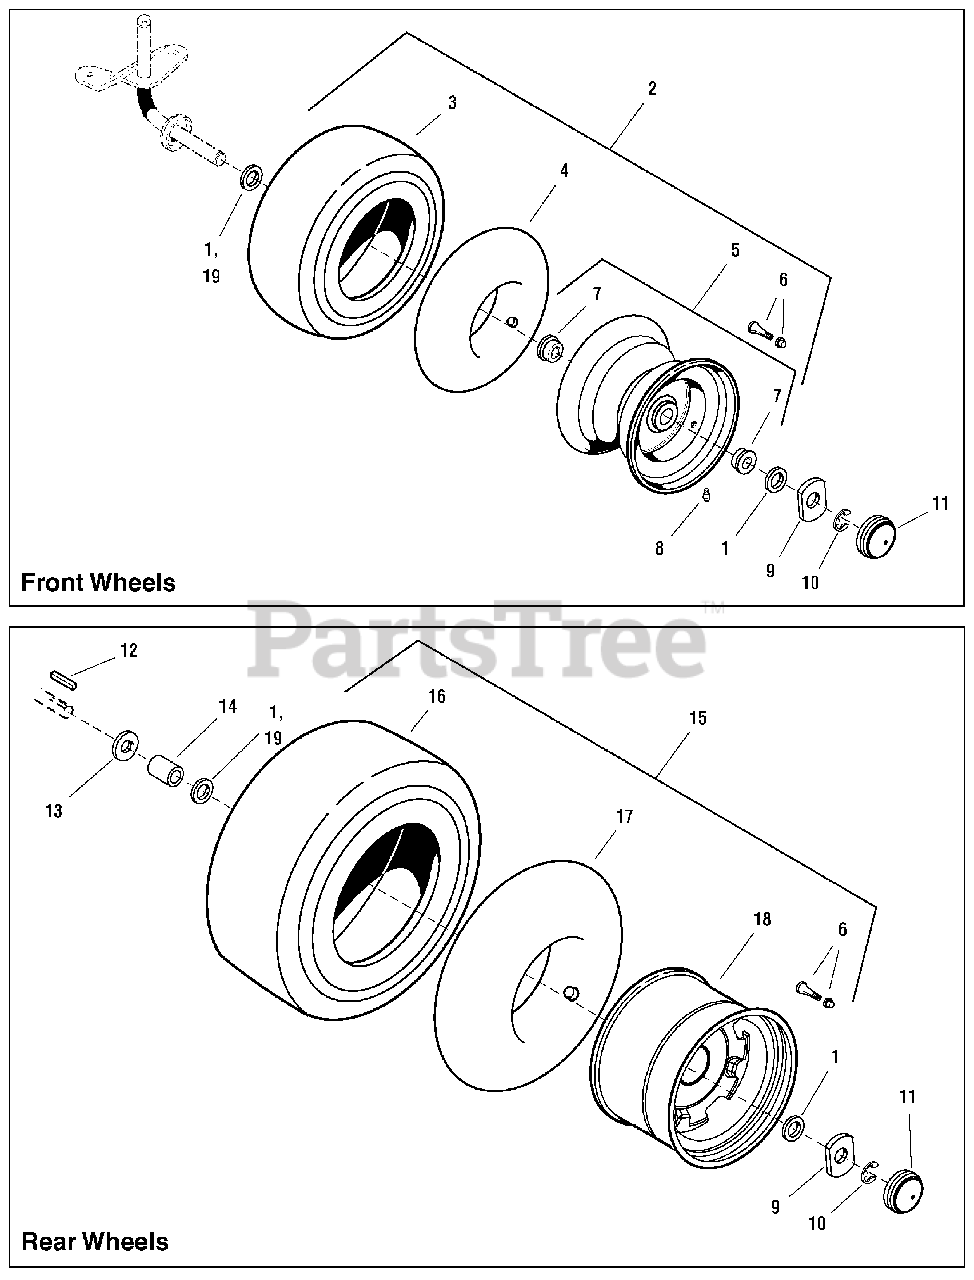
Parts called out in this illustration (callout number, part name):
1	WASHER, 3/4
1	WASHER, Flat
2	WHEEL & TIRE ASSEMBLY, Front
3	TIRE, Turf 15 X 6.00 - 6 Saver TL
4	TUBE, Tire, Front
5	WHEEL & BUSHINGS ASSEMBLY, Front
6	VALVE STEM & CAP
7	BEARING
8	FITTING, Grease, 1/4-28 Thread
9	WASHER, Special Yellow
10	RING, Retaining
11	CAP, Hub
12	KEY, 3/16 x 3/16 x 3
12	KEY, 3/16 x 3/16 x 2
13	WASHER
14	SPACER, 3/4 ID x 1-1/4 OD x 1-5/8
15	WHEEL & TIRE ASSEMBLY, Rear 20"
15	WHEEL & TIRE ASSEMBLY, Rear 22"
16	TIRE, Turf 20 X 8.00 - 8 Saver TL
16	TIRE, 20 x 830-8, 2 Ply, K358
16	TIRE, 22 x 10.00-8, 2 Ply, K358
17	TUBE, Tire, Rear
18	WHEEL, Hub
19	WASHER, Flat, 3/4 x 1-1/4
